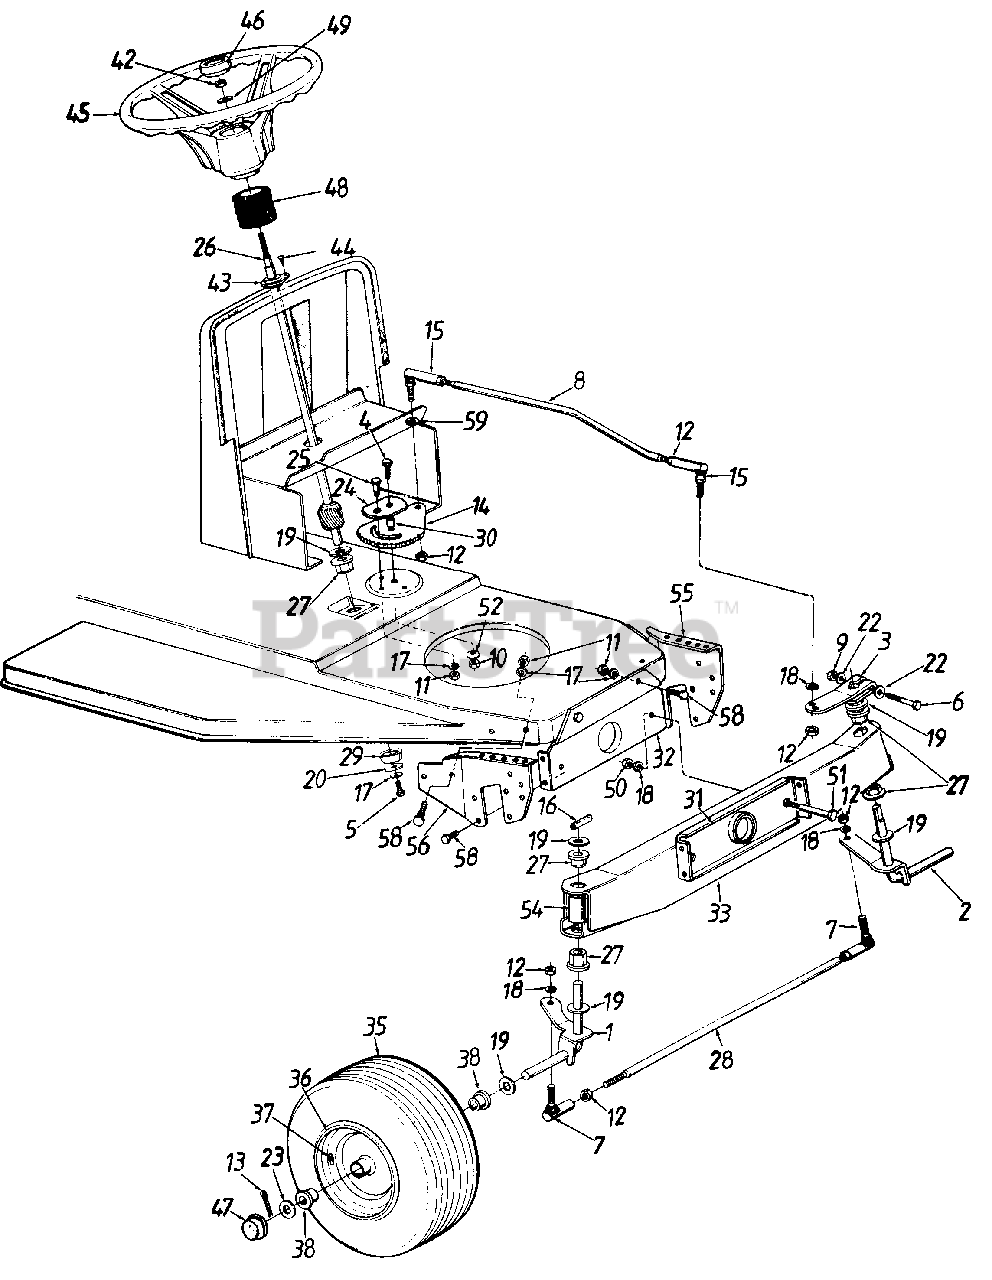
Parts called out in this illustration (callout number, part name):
1	Front Axle Ass'y.-R.H.
2	Front Axle Ass'y.-L.H.
3	Steering Arm
4	Hex Bolt 3/8-24 x 1" Lg.
5	Hex Bolt 5/16-18 x .62"
6	Hex Bolt 5/16-24 x 2" Lg.
7	Ball Joint 3/8-24 Thd.
8	Steering Drag Link
9	Hex L-Nut 5/16-24 Thd.
10	Hex Nut 3/8-24 Thd.
11	Hex Nut 5/16-18 Thd.
12	Hex Jam Nut, 3/8-24 Thd.
13	Cotter Pin 1/8 Dia.
14	Steering Gear Segment
15	Drag Link Ball Joint 3/8-24 0 Thd.
17	L-Wash. 5/16" I.D.
18	L-Wash. 3/8" I.D.
19	Fl-Wash. .64" I.D. x 1.24"
20	Fl-Wash. .340" I.D. x 1.125"
22	Spr. Wash. .32" I.D. x .62"
23	Fl-Wash. .635" I.D. x 1.585"
24	Retainer Plate
25	Shld. Bolt .437" Dia. x .350"
26	Steering Shaft
27	Hex Flange Brg. .634 Dia.
28	Tie Rod 20" Lg.
29	Spacer .985" I.D.
30	Spacer .380" I.D.
35	Front Wheel Ass'y. Comp. 15" x 6"
36	Rim Ass'y. Only
37	Air Valve
38	Bronze Bearing .63" I.D.
42	Hex L-Nut 5/16-24 Thd.
43	Steering Column Brg.
44	Cr-Sunk Scr. #10 x 5/8n Lg.
45	Steering Wheel
46	Steering Wheel Cap
47	Hub Cap
48	Bellow Steering Column
49	Bell-Wash. .345" I.D. x .88"
50	Hex Nut 3/8-16 Thd.*
51	Shld. Bolt 1/2" Dia. x 2.04n
52	Bell-Wash. .39" x 1.38" O.D.
54	Plastic Tube
55	Pivot Bar Side Plate-L.H.
56	Pivot Bar Side Plate-R.H.
58	Hex Wash. Tap Scr. 5/16-18 x .62" Lg.
59	L-Wash. 3/8" I.D.
